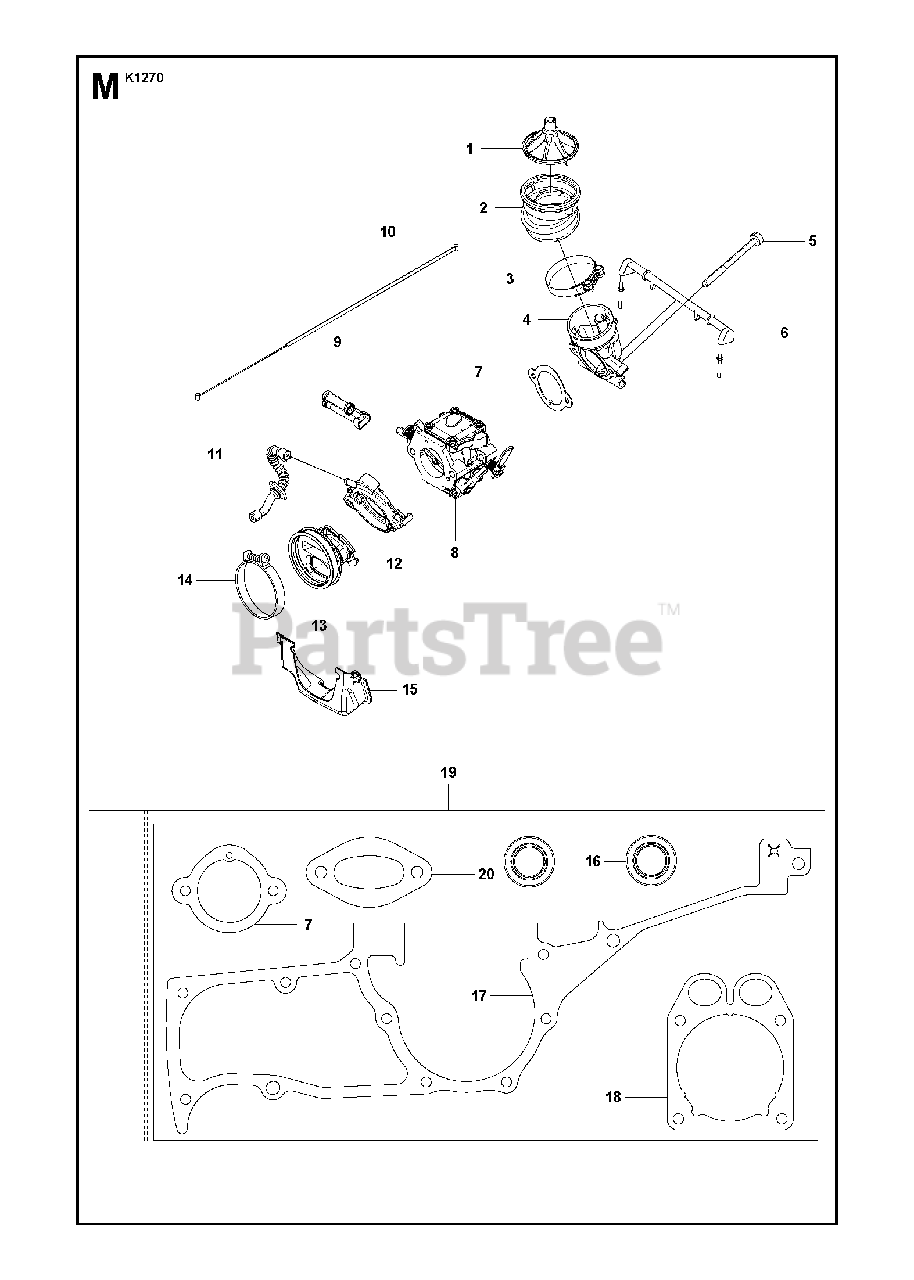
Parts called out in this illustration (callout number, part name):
3	HOSE CLAMP
5	SCREW ITXSCM
16	SEALING RING
